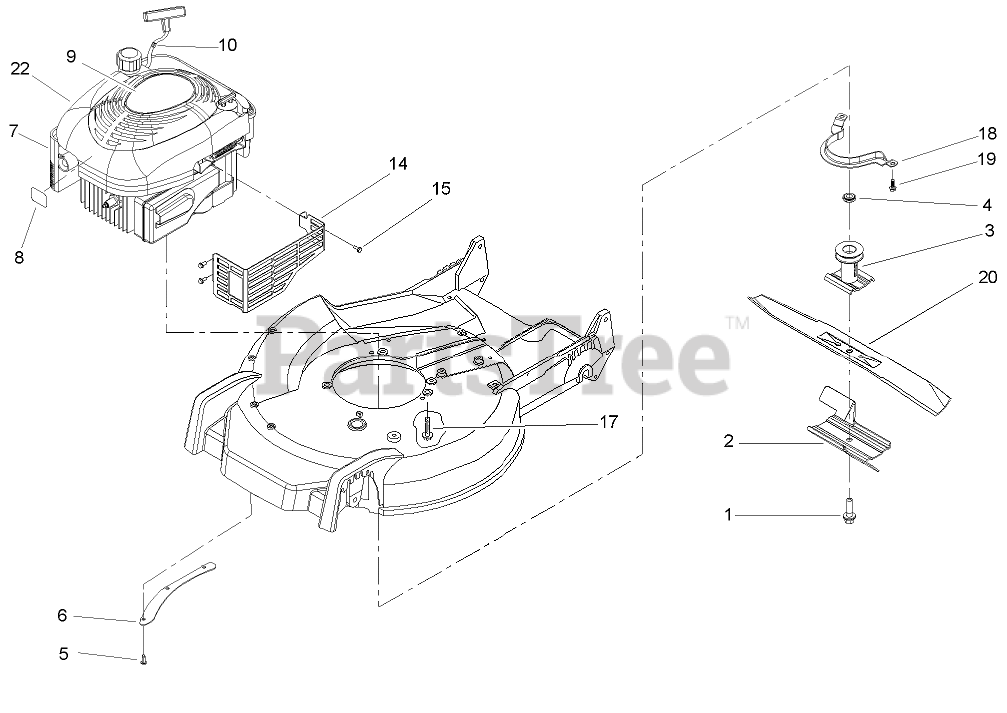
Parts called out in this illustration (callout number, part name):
1	BOLT-BLADE
2	Accelerator-Blade
3	DRIVER-BLADE
4	Spacer-Driver
5	SCREW
6	SHEET-LIP
8	Decal
10	STOP-ROPE
14	SHIELD-MUFFLER
15	SCREW-TAPTITE
17	SCREW-HWH
18	BRACKET-GUIDE, BELT
19	SCREW-HWHTF
20	BLADE
22	Shroud-Quantum
